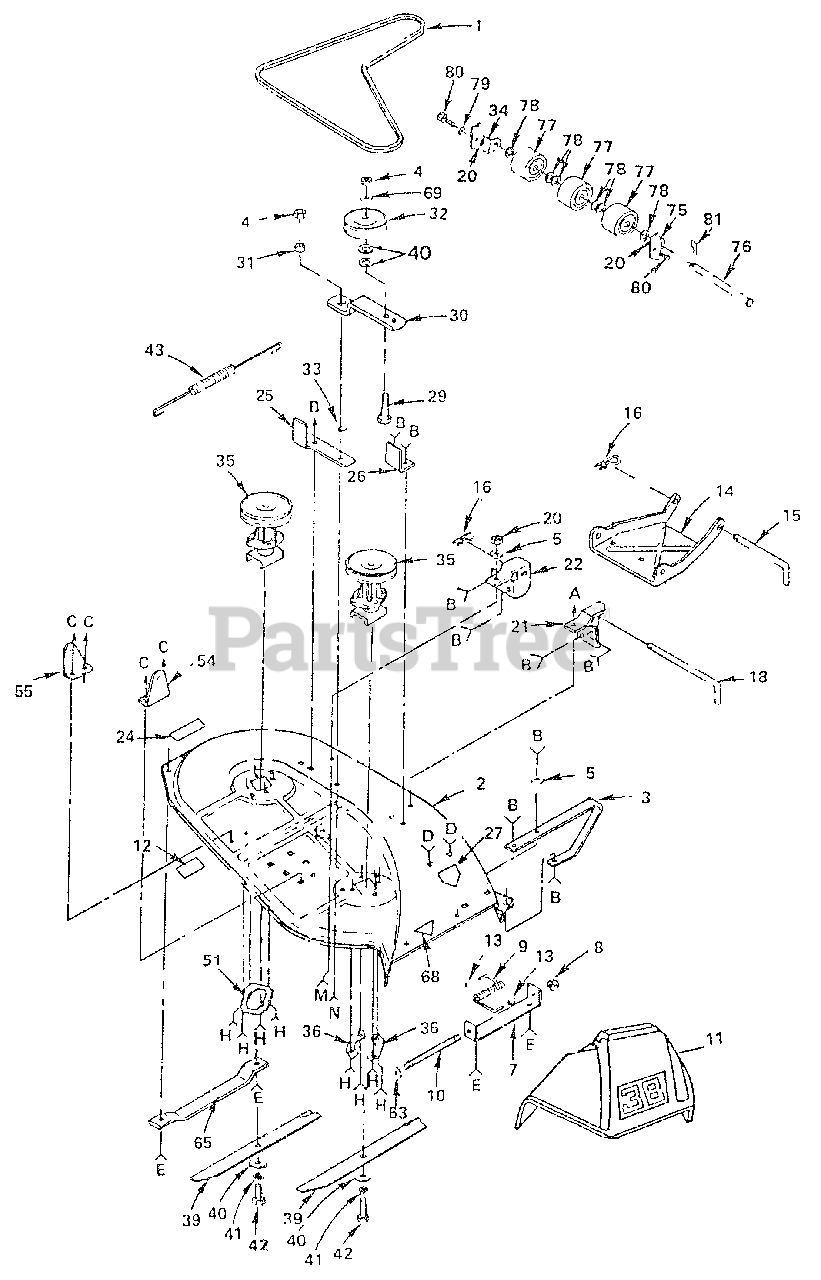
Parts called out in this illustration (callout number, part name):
2	Housing Assembly - Mower
3	Runner - R.H.
4	Nut - Lock, 3/8-16
5	Washer - 11/32 x 3/4 x 16 Ga.
7	Bracket - Deflector
9	Spring - Deflector
10	Rod - Hinge
11	Deflector- Shield
12	Decal - V-Belt Schematic
14	Link - Parallel
15	Pin - Hinge,Front
16	Spring - Retainer
18	Pin - Hinge, Rear
20	Nut - Lock 5/16-18
21	Bracket - Lift, R.H.
22	Bracket - Lift, L.H.
24	Instruction - Caution Decal
25	Support-Arm
26	Stop - Deck, Front
27	Decal - Safety Standard (Model YT140CR)
29	Bolt - 3/8-16 x 2
30	Arm - Idler
32	Pulley - Idler
33	Washer-Wear, 1/16
34	Bracket - Nose Roller, L.H.
35	Mandrel Assembly
36	Plate - Support, Mandrel
39	Blade - 38"
40	Washer- 13/32 x 1-1/4 x 12 Ga.
41	Washer - Lock, 3/8
42	Bolt - Hex 3/8-24 x 1-1/2 Gr.5
43	Spring - Ext.
51	Plate - Support
54	Bracket - Suspension., Rear, R.H.
55	Bracket - Suspension., Rear, L.H.
63	Washer-11/32 x 5/8 x 16 Ga.
65	Runner- L.H.
68	Decal - Warning
69	Washer- 13/32 x 13/16 x 16 Ga.
75	Bracket - Nose Roller, R.H.
76	Pin - Pivot
77	Roller- Nose
78	Washer -15/32 x 1 x 10 Ga.
79	Washer -15/32 x 1 x 16 Ga.
80	Bolt - Hex 5/16-18 x 3/4
81	Cotter Pin - 1/8 x 3/4
